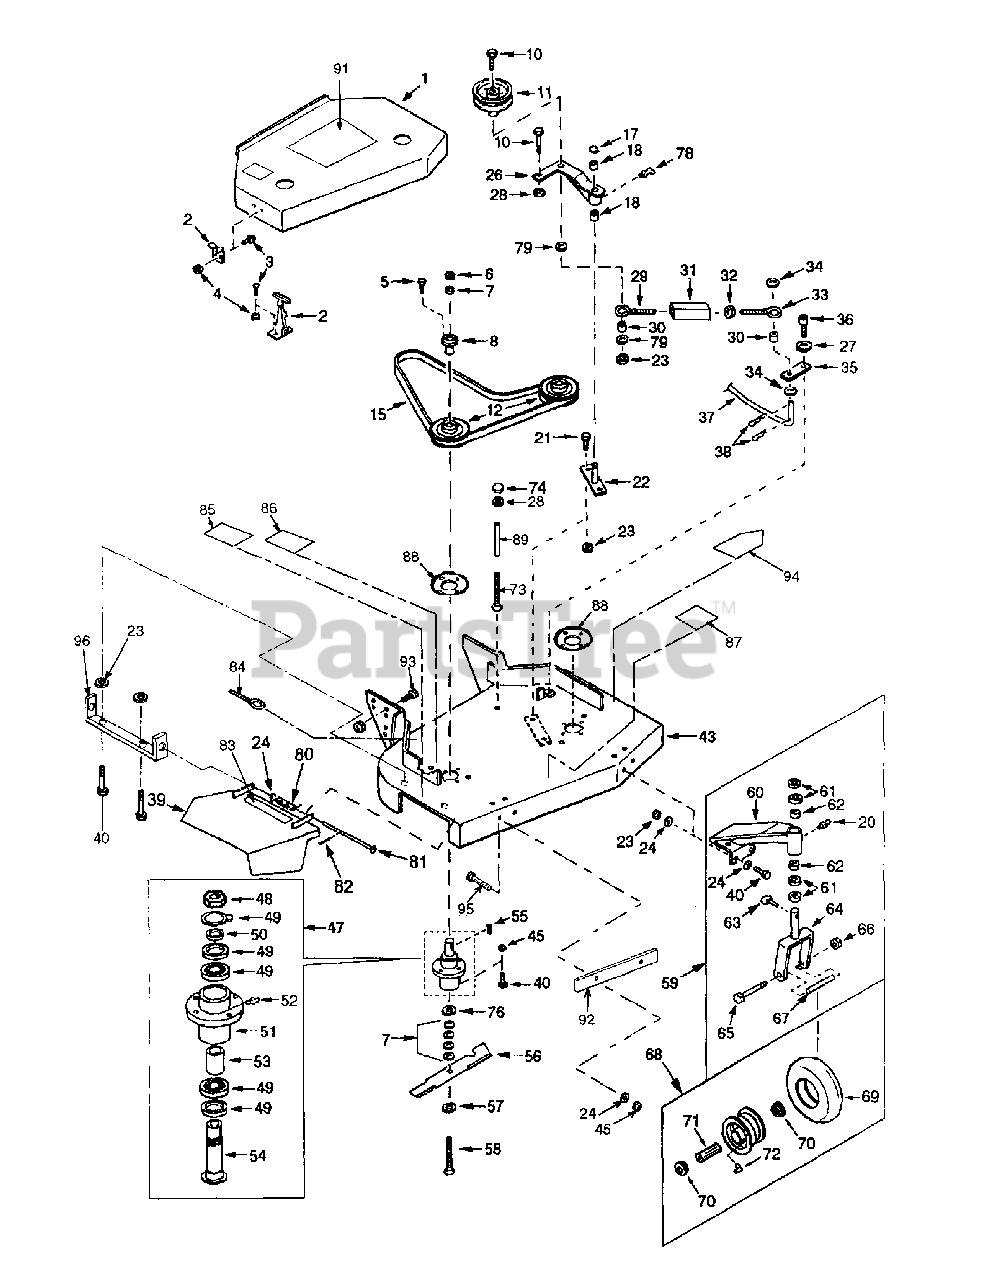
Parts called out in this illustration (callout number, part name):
1	36" Deck Cover
2	Rubber Latch
3	Machine Screw, 10-24 x 1/2 Round Hd.
4	Hex Nut, 10-24 Nylock
5	Cap Screw, 1/4-20 x 3/4 Hex Hd.
6	Hex Nut, 5/8-11
7	Blade Spacer
8	Pulley Bushing
10	Cap Screw, 3/8-16 x 2-1/2 Hex Hd.
11	Idler, Deck Take-up
12	Deck Pulley
15	Drive Belt (36" Deck)
17	E-Ring, External
18	Sintered Bushing
20	Grease Fitting, 1/4-28, Taper, Str.
21	Cap Screw, 3/8-16 x 1 Hex Hd.
22	Idler Pivot
23	Hex Nut, 3/8-16 Nylock
24	Flat Washer, 3/8, Small O.D.
26	Pivot Arm, Deck Take-up Idler Pulley
27	Shim Washer, 3/4 x 1/2 x 1/16
28	Hex Nut, 3/8-16
29	Eyebolt, L.H.
30	Sleeve
31	Turnbuckle (36" Deck)
32	Hex Nut, 5/16-18
33	Eyebolt, R.H.
34	Flat Washer, 3/8, Large O.D.
35	Clutch Link
36	Shoulder Bolt, 1/2 X 3/8
37	Rod, Blade Clutch
38	Hairpin, 3/8-7/16
39	Discharge Chute
40	Cap Screw, 3/8-16 x 1-1/4 Hex Hd.
43	36" Cutter Deck
45	Hex Nut, 3/8-16 Stover
46	Belt Guide
47	Spindle Assembly
48	Hex Nut, 1-1/8-12 UNF, Jam
49	Kit, Spindle Repair
50	Seal Spacer
51	Spindle Housing
52	Grease Fitting
53	Internal Spacer
54	Spindle
55	Key, 1/4 x 1/4 x 2
56	Rotary Blade, 16-1/2"
56	Rotary Blade, 18"
57	Flat Washer, 5/8
58	Cap Screw, 5/8-11 x 9-1/2 Hex Hd.
59	Caster Assembly
60	Caster Bracket
61	Caster Spacer
62	Bushing, Caster Bracket
63	Lynch Pin, 7/16 x 1-7/8
64	Caster Yoke
65	Cap Screw, 1/2-13 x 5-1/2 Hex Hd.
66	Hex Nut, 1/2-13 Nylock
67	Sleeve, Caster Wheel Bearing
68	Caster Wheel Assembly
69	Tire, Caster Wheel
70	Bearing Retainer, Caster Wheel
71	Roller Bearing, Caster Wheel
72	Grease Fitting, 1/4-28, 45°.
74	Protective Cap
75	Channel, Rubber
76	Flat Washer, 1-1/2 x 5/8 x .055
77	Flat Washer, 3/8, Thick
78	Grease Fitting
79	Flat Washer, 5/16 USS
80	Torsion Spring
81	Deflector Pivot Pin Ass'y
82	Cotter Pin, 1/8 x 1
83	Decal, "Width of Cut"
84	Belt, Rod, Tensioner
85	Decal, Rotating Blade
86	Decal, Warning Safety
87	Decal, Warning Shield
88	Plate, Spindel Backing
89	Spacer, Belt Guard
90	Bracket, Deflector Pivot
91	Label, Command Deck
93	Bolt, Carriage
94	Decal, Danger
95	Bolt, Carriage
96	Bracket Deflector
